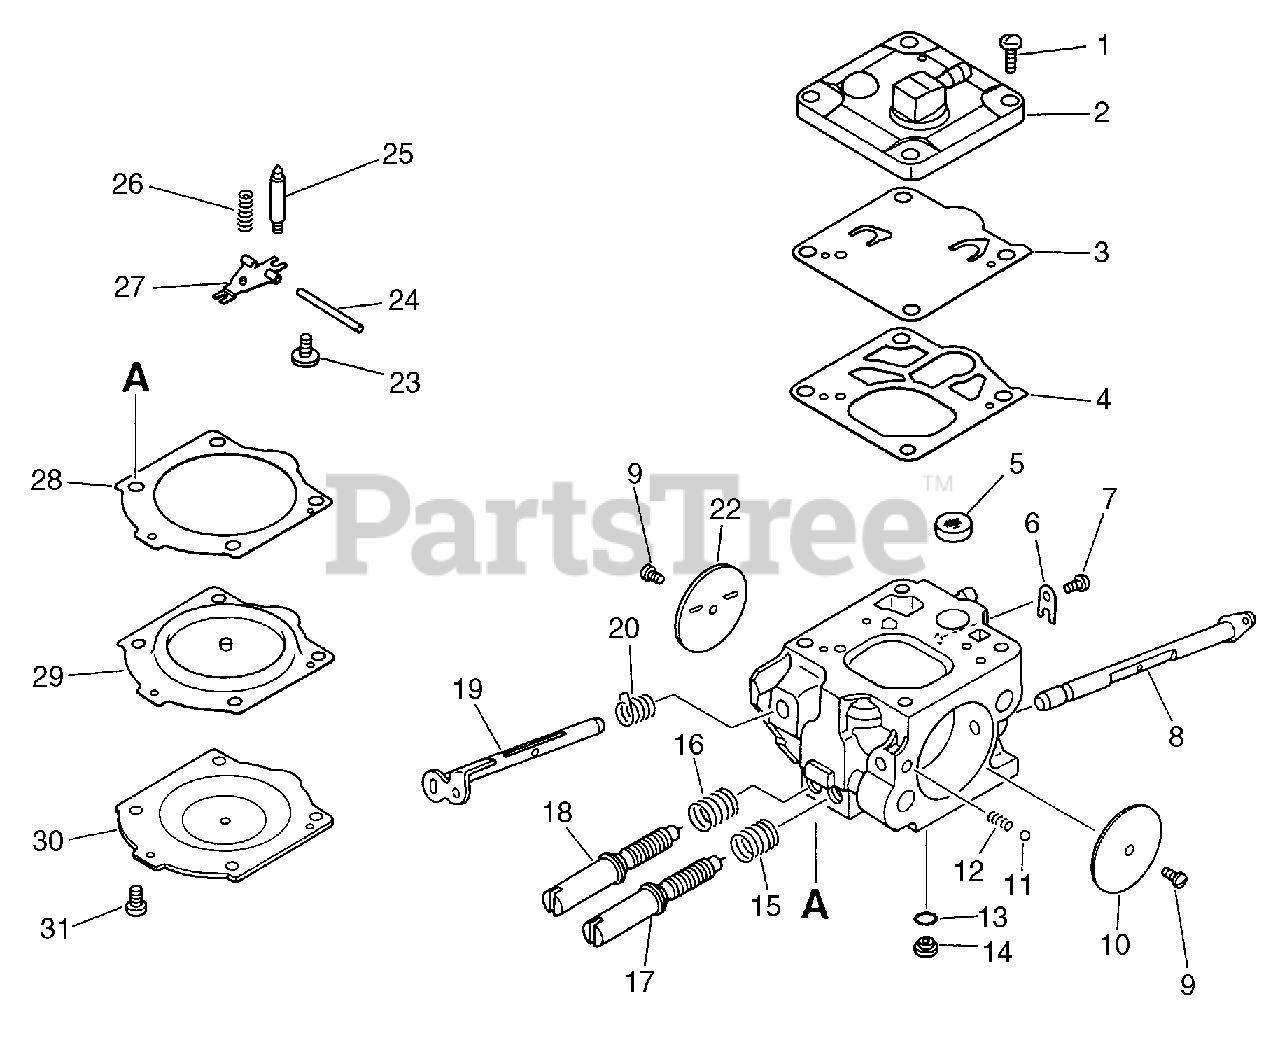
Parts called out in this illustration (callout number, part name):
1	SCREW
2	COVER, FUEL PUMP
3	GASKET, PUMP
4	DIAPHRAGM, PUMP
5	FILTER, FUEL
6	CLIP, THROTTLE SHAFT
7	SCREW
8	SHAFT, CHOKE
9	SCREW
10	VALVE, CHOKE
11	BALL, CHOKE SET
12	SPRING, CHOKE SET
13	PLUG, WELCH - LARGE
14	VALVE, CHECK
15	SPRING
16	SPRING
17	NEEDLE, HIGH SPEED
18	NEEDLE, IDLE
19	SHAFT, THROTTLE
20	SPRING, RETURN
22	VALVE, THROTTLE
24	PIN, METERING LEVER
25	VALVE, INLET NEEDLE
26	SPRING, TENSION
27	LEVER, METERING
28	GASKET, METERING DIAPHRAGM
29	DIAPHRAGM
30	COVER, DIAPHRAGM
31	SCREW
